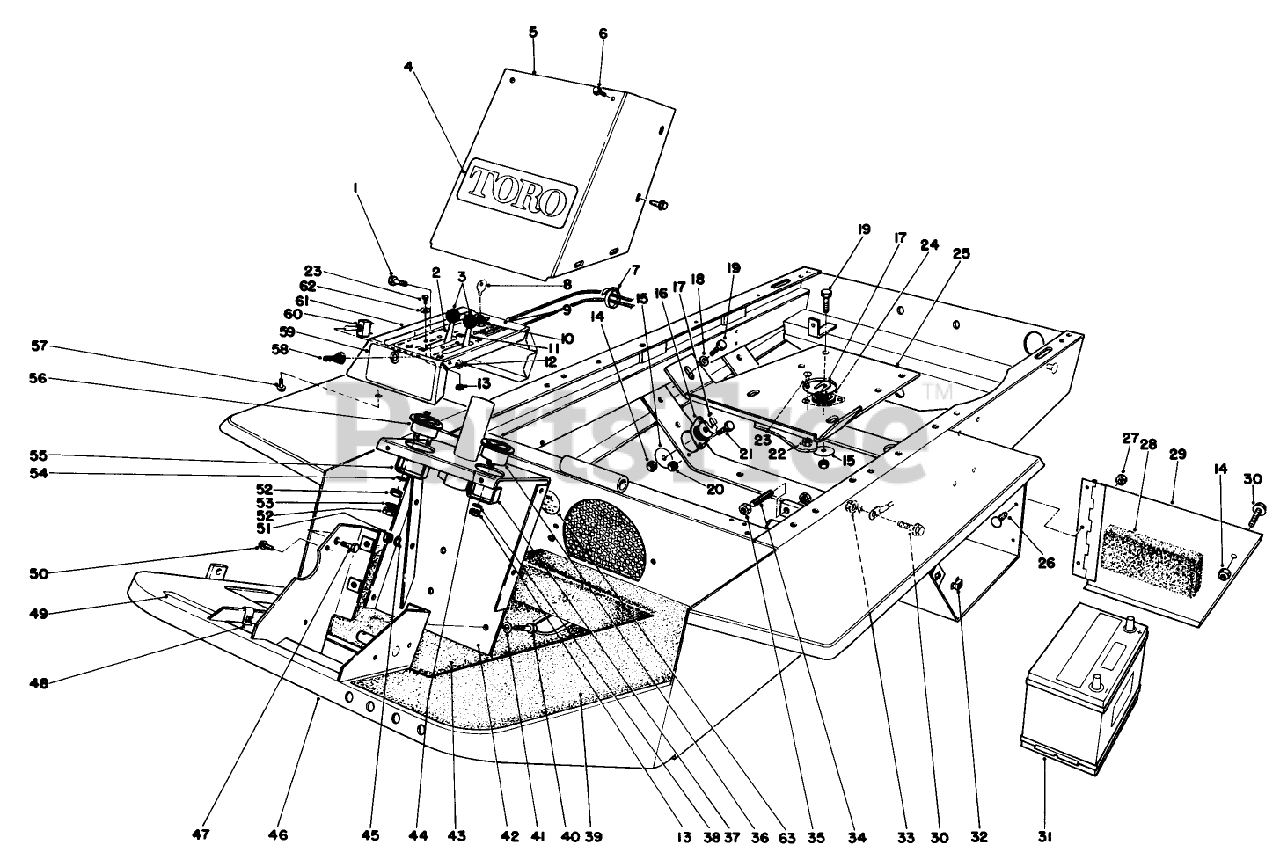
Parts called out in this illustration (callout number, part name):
1	SCREW-HH
2	CHOKE CONTROL
6	SCREW-HHFTF
7	TIE-CABLE
10	SWITCH
11	THROTTLE CONTROL
12	WASHER-FLAT
13	NUT-HEX
14	NUT-LOCK, NI
15	WASHER
16	ENGINE RUBBER MT
17	SHIM-AXLE
18	WASHER-FLAT
19	SCREW-HH
20	NUT-LOCK, NI
21	SCREW-HH
22	NUT-LOCK, NI
23	10-24 X 5/8 PAN HD MS
24	RUBBER MOUNT
26	SCREW-HSBH
27	NUT-LOCK, NI
28	BATT BOX FOAM
30	SCREW-HHF
31	Battery Assy.
32	Retained Nut
33	NUT-HHF, WHIZ
35	NUT-JAM
37	BRACKET
38	WASHER-LOCK, INT
39	NON SKID (TUNNEL)
40	SCREW-HH
41	WASHER-LOCK
43	NON-SKID-FLOOR
45	WASHER-LOCK
46	FRAME ASM
47	SCREW-HH
50	SCREW-HWH
51	NUT-HEX
52	NUT-HEX
53	WASHER-LOCK
54	WASHER-FLAT
55	MTG CLAMP F/W GUAGE
57	SCREW-HWHTF
58	BOOT-SWITCH
59	BY-PASS DECAL
60	SWITCH & BOOT ASM
62	WASHER-LOCK
63	DECAL-OIL
